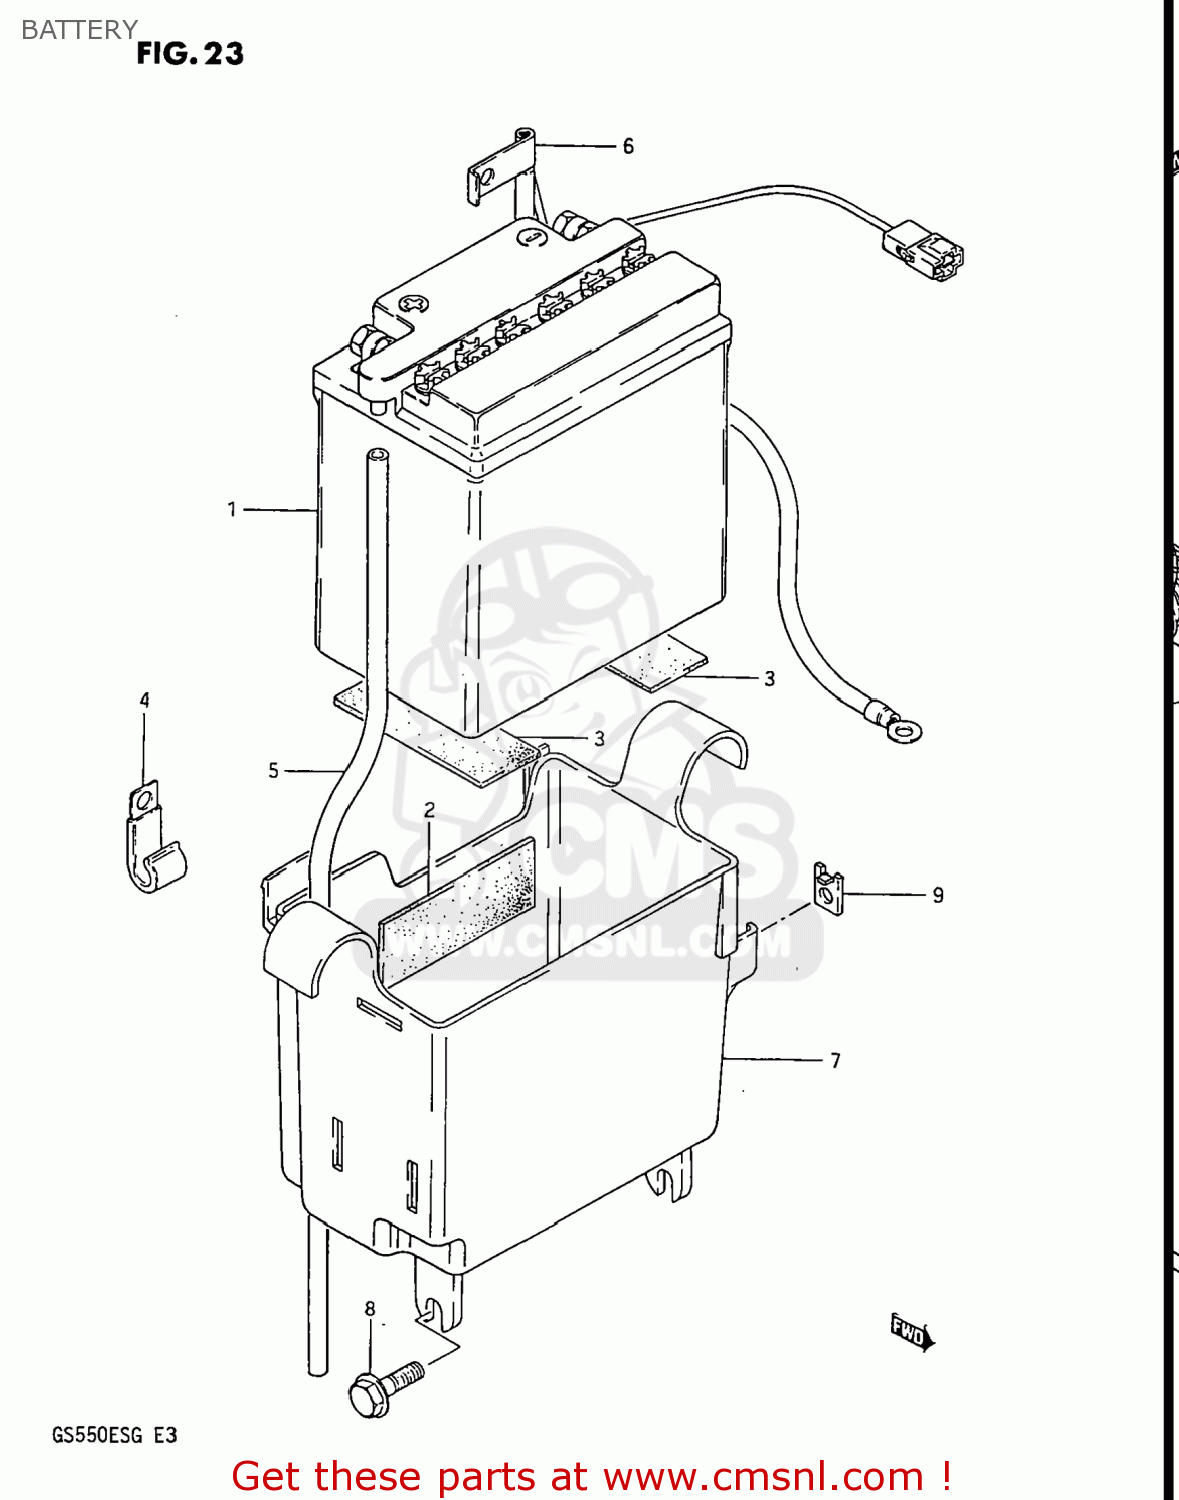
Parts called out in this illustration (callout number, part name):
1	BATTERY ASSEMBLY (12V)
2	PROTECTOR(30X80X2)
3	PROTECTOR,20X9
4	CLAMP
5	HOSE,BATTERY EXHAUST
6	WIRE,STARTER MOTOR LEAD
7	HOLDER,BATTERY
8	BOLT
9	WASHER,IGNITER
